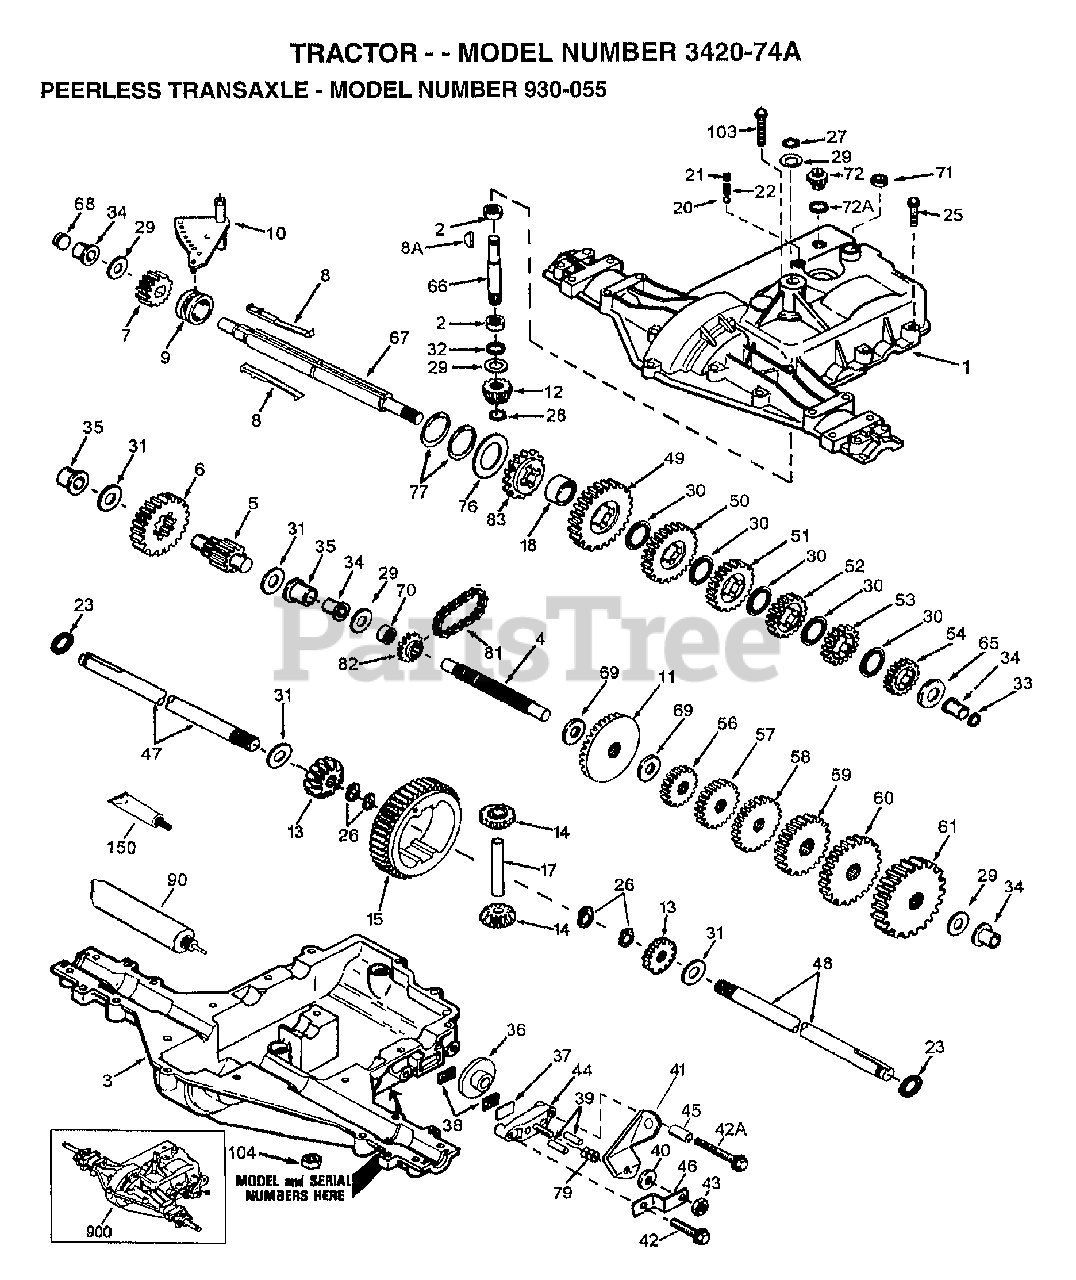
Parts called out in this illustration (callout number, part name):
1	TRANSAXLE COVER
2	BEARING, NEEDLE
3	TRANSAXLE CASE
4	SHAFT, COUNTER
5	OUTPUT SHAFT AND PINION
6	GEAR, OUTPUT
7	GEAR, SPUR, 15 TEETH
8A	KEY, WOODRUFF
9	COLLAR, SHIFTER
10	ROD & FORK ASSY, SHIFT
11	GEAR, BEVEL, 42 TEETH
12	BEVEL PINION, INPUT
13	GEAR, BEVEL
14	GEAR, BEVEL, PINION
18	SPACER, NEUTRAL
20	BALL STEEL, 5/16" DIA.
21	SCREW, 3/8-16 X 3/8"
25	SCREW, 1/4-20 X 1-1/4
26	RING RETAINER
27	RING, RETAINER
28	RETAINING RING
29	WASHER THRUST
30	WASHER THRUST
33	SEAL, SQUARE CUT
34	BUSHING, FLANGED
35	BUSHING, FLANGED
36	DISK, BRAKE
37	PLATE BRAKE PAD
41	BRAKE LEVER
42	SCREW, 1/4-20 X 1-1/4
42A	SCREW, 1/4-20 X 2-1/4
43	LOCKNUT 5/16-24
44	HOLDER BRAKE PAD
46	BRKT BRAKE LEVER
49	GEAR, SPUR, 37 TEETH
50	GEAR, SPUR, 35 TEETH
51	GEAR, SPUR, 30 TEETH
52	GEAR, SPUR, 25 TEETH
53	GEAR, SPUR, 22 TEETH
54	GEAR, SPUR, 19T
56	GEAR, SPUR, 12 TEETH
57	GEAR, SPUR, 15 TEETH
58	GEAR, SPUR, 20 TEETH
59	GEAR, SPUR, 25 TEETH
60	GEAR, SPUR, 28 TEETH
61	GEAR, SPUR, 31 TEETH
65	WASHER, THRUST
66	SHAFT, INPUT
67	SHAFT, BRAKE, 4 KEYED
69	WASHER THRUST
71	SEAL SQUARE CUT
72	THREADED PLUG 9/16-18
76	WASHER, THRUST
77	INVERTED RETAINING RING
81	CHAIN, ROLLER
82	SPROCKET 9T
83	SPROCKET 18T (REV)
90	GREASE BENTONITE, 32 OZ.
150	GASKET ELIMINATOR
900	REPLACEMENT TRANSAXLE
